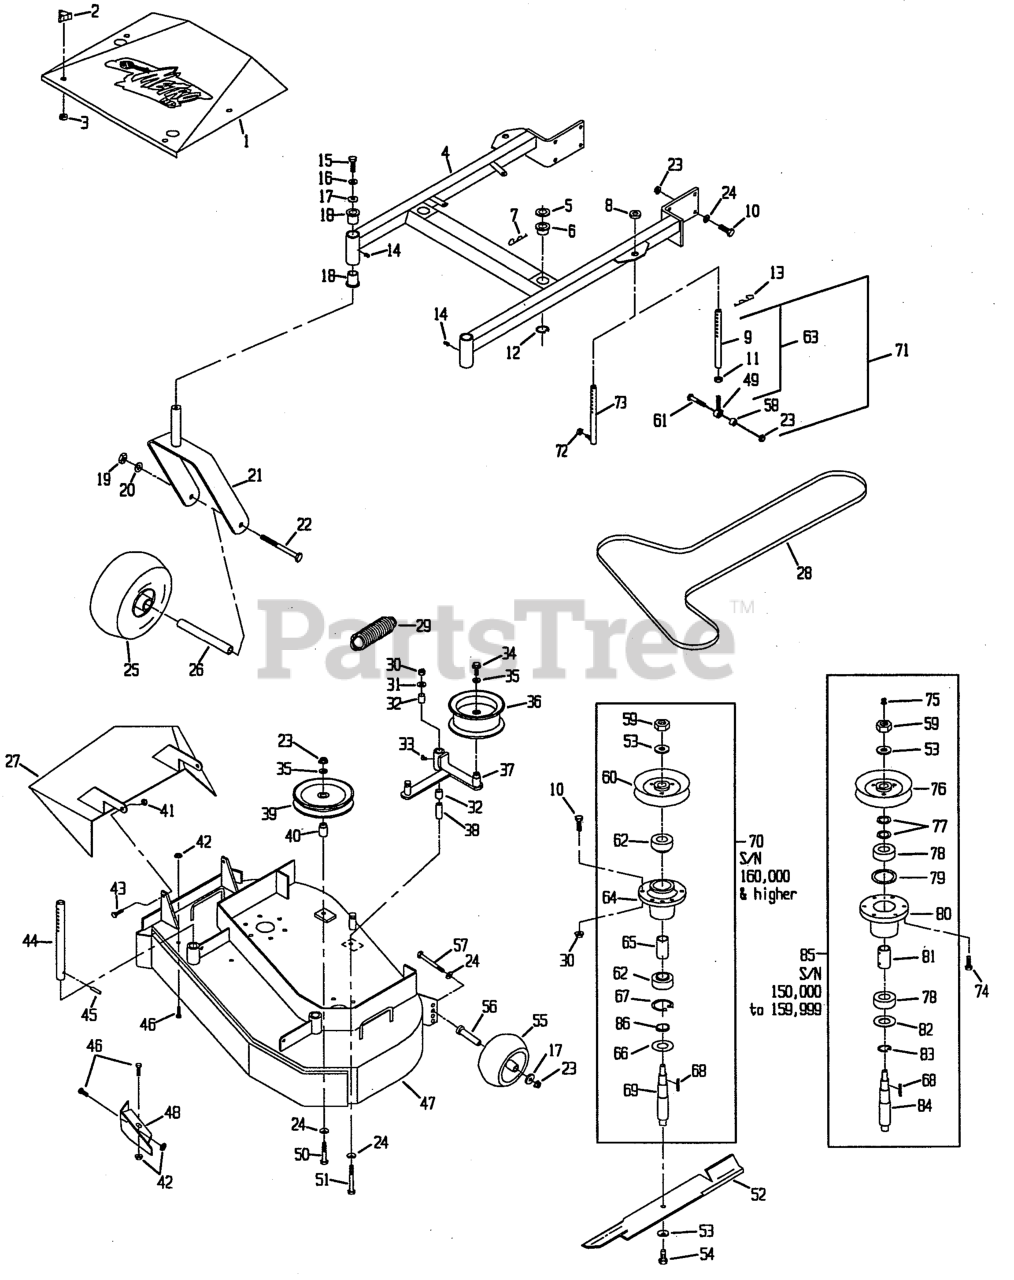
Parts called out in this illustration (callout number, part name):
1	Shieid, Belt W/Decals
2	Knob, Belt Shield
3	Washer, Belt Cover
4	Support Weldmt W/Bushings &Decals
5	Spacer, Front Deck Support
6	Bushing, Deck Support
7	Hairpin, Cotter
8	Spacer, Blade Drive
9	Link, Deck Support
10	Screw.Hex Cap 3/8-16x1-1/4
11	Nut, Reg Hex 3/8-24
12	Ring, Retaining
13	Hairpin, Cotter
14	Zerk, Straight 1/8
15	Screw, Hex Cap 3/8-16x1
16	Washer, 3/8 Heavy Spring
17	Washer, Swivel
18	Bearing, Flange
19	Nut, Reg Hex 1/2-13
20	Washer, Lock Hlcl Spg 1/2 Reg
21	Caster Weldmt
22	Screw, Hex Cap 1/2-13x6
23	Nut, Whizlock 3/8-16
24	Washer, Disc Spring 3/8
25	Tire & Wheel Assembly
26	Spacer
27	Chute Weldmt, Discharge
28	Belt, Deck Drive
29	Spring, Extension
30	Nut, Nyloc 3/8-16
31	Washer, Flat Std 3/8
32	Pivot, Bearing
33	Zerk, 90 Degree 1/4-28
34	Bolt, Hex Whizlock 3/8-16x1
35	Washer, Flat 3/8 SAE
36	Pulley, Idler
37	Arm, Weldmt
38	Bushing, Idler Pivot
39	Pulley, Idler
40	Bushing, Idler
41	Nut, Nylock 5/16-18
42	Nut, Whizlock 5/16-18
43	Screw, Hex Cap 5/16-18x1
44	Rod, Deck Support
45	Rollpin, 1/4x1-1/2
46	Screw, Hex Cap 5/16-18x5/8
47	Deck Weldmt W/Decals, Discharge Baffle & Support Rods
48	SPACER-WHEEL
49	Ball Joint
50	Screw, Hex Cap 3/8-16x2-3/4
51	Screw, Hex Cap 3/8-16x3-1/2 G8
52	Blade, 16.25
53	Washer, Spring Disc
54	Screw, Hex Cap 5/8-11x1
55	Roller, Antiscalp
56	Bushing, Roller
57	Screw, Hex Cap 3/8-16x4 G8
58	Bushing Spacer
59	Nut, Reg Hex 5/8-18
60	Sheave W/Hub
61	Screw, Hex Cap 3/8-16x1-3/4
62	Bearing
63	Link, Assembly
64	Housing, Spindle
65	Spacer, Bearing
66	Guard, Bearing-Bottom
67	Ring, Snap
68	Key, Machine
69	Shaft, Spindle
70	Housing, Cutter Assembly
71	Kit, Link Assembly
72	Nut, Torque 3/8-24
74	Screw, Hex Taptite 3/8x16x1
75	Zerk, Straight 1/4-28
76	Sheave W/Hub
77	Washer, .060
78	Bearing, Spindle
79	O-Ring, Cutter Housing
80	Housing, Bearing
81	Spacer, Bearing
82	Seal, Dust
83	Ring, Snap
84	Shaft, Spindle
86	Spacer
